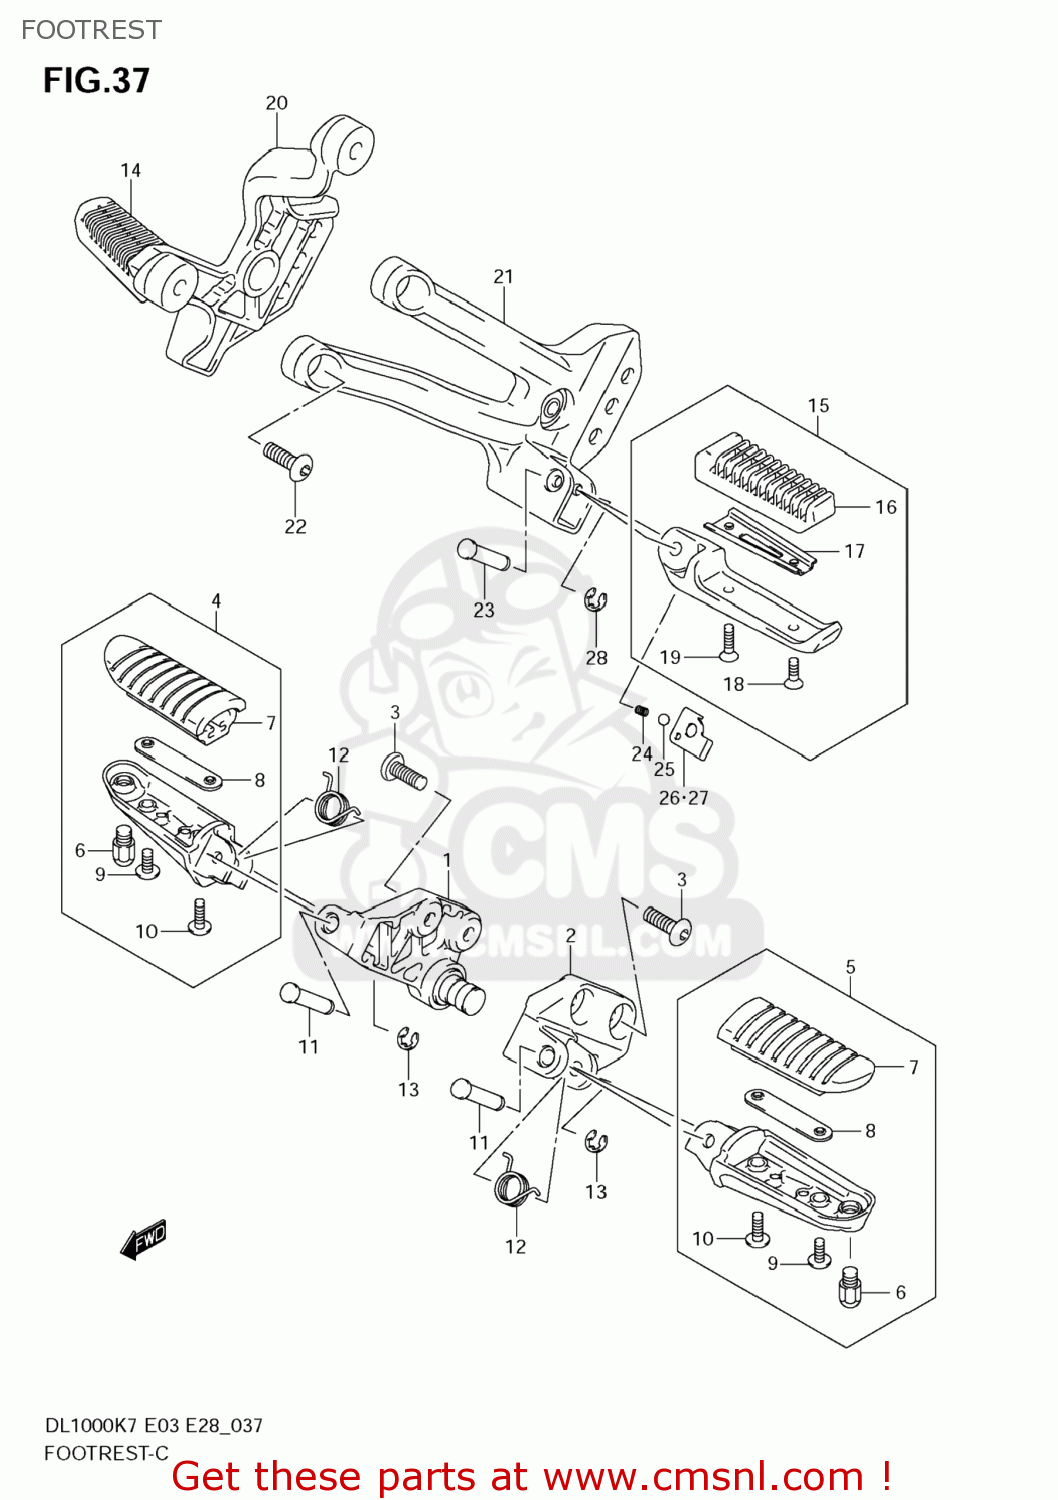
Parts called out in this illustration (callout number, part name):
1	BRACKET,FR FOOTREST,R
2	BRACKET,FR FOOTREST,L
3	BOLT(8X23)
4	FOOTREST ASSY,FR,R
5	FOOTREST ASSY,FR,L
6	BOLT,BANK SENSOR
7	RUBBER,FOOTREST
8	PLATE,FR FOOTREST RUBBER
9	SCREW
10	SCREW
11	PIN
12	SPRING
13	E RING
14	FOOTREST ASSY,PILLION,R
15	FOOTREST ASSY,PILLION,L
16	RUBBER,RR FOOTREST
17	PLATE,RUBBER STOPPER
18	SCREW
19	SCREW
20	BRACKET,PILLION FOOT,R(BLACK)
21	BRACKET,PILLION FOOT,L(BLACK)
22	BOLT(8X23)
23	PIN(8X33.2)
24	SPRING
25	BALL
26	PLATE,PILLION FOOTREST,R
27	PLATE,PILLION FOOTREST,L
28	E RING
